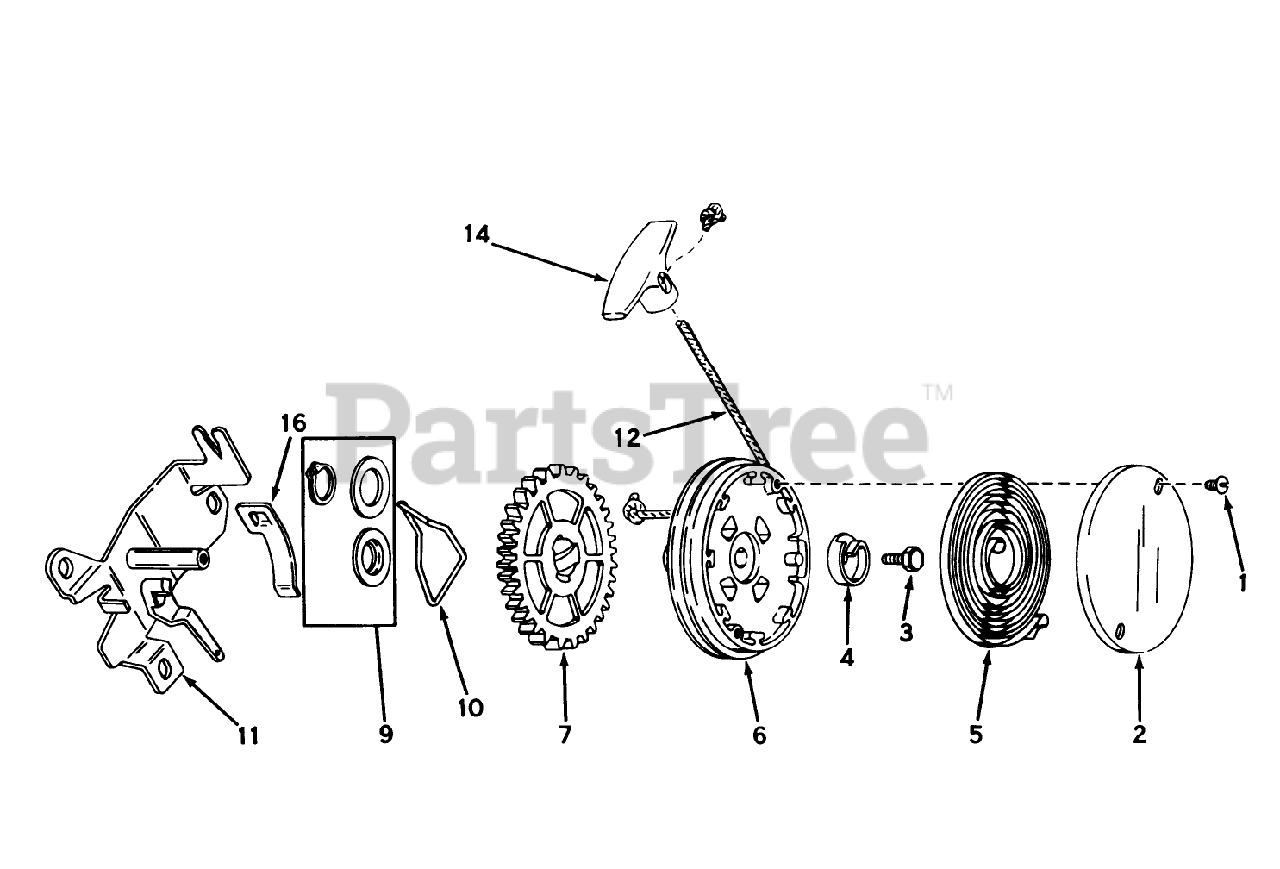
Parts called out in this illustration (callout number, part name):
1	Screw
2	Cover, Spring
3	Screw, Hex Washer Head
4	Hub Spring
5	Spring, Rewind
6	Pulley Assy. (Incl. No. 9)
9	Kit, Thrust Wash. Snap Rg.
10	Brake
11	Bracket Assy., Mounting
12	Rope-Starter
14	Handle-Starter
16	Clip Rope
